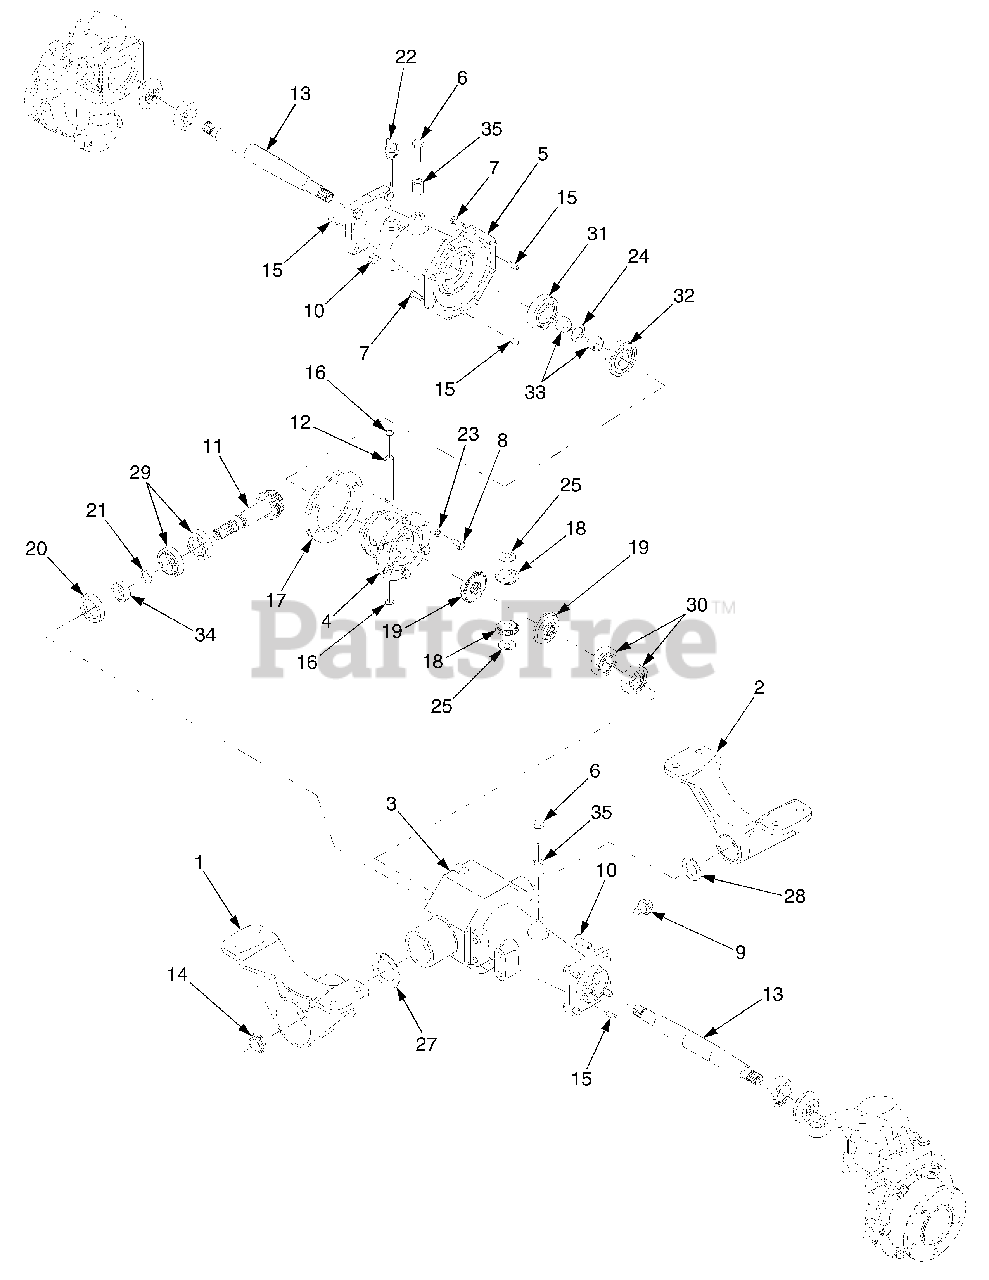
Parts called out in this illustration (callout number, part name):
1	Bracket, Front Axle Mtg. - Rear
2	Bracket, Front Axle Mtg. - Front
3	Housing, Main Axle RH
4	Housing, Differential
5	Housing, Axle LH
6	Screw, Hex Cap, M10-1.5 x 35 GR8.8
7	Screw, Hex Cap, M8-1.25 x 25 GR8.8
8	Screw, Hex Cap, M8-1.25 x 14 GR8.8
9	Plug, Screw, M14-1.5 x .827
10	Screw, Hex Lock, M10-1.5 x 30
11	Shaft, Input, 6T
12	Shaft, Cross
13	Shaft, Axle
14	Nut, Special, 24mm
15	Pin, Dowel, 8mm x 20mm
16	Ring, Internal Retaineng, 14mm
17	Gear, Bevel, 34T
18	Gear, Miter, 10T
19	Gear, Miter, 16T
20	Seal, Oil, 52mm x 35mm x 10mm
21	O-Ring, 19mm x 3mm
22	Dipstick, Front Axle
23	Washer, Flat, .33 x .63 x .0635
24	Washer, Flat, .793 x 1.24 x .06 Hdn.
25	Washer, Special Spherical
26	Washer, Flat, .793 x 1.37 x .005
26	Washer, Flat, .793 x 1.37 x .010
26	Washer, Flat, .793 x 1.37 x .015
26	Washer, Flat, .793 x 1.37 x .020
26	Washer, Flat, .793 x 1.37 x .025
27	Washer, Thrust, 1.66 x 2.59 x .059
28	Washer, Thrust, 1.03 x 1.73 x .059
29	Bearing, Tapered Roller w/ Race
30	Bearing, Ball
31	Bearing, Ball
32	Bearing, Ball
33	Spacer, 20 x 25 x 16mm
34	Spacer, 25 x 35 x 12mm
35	Spacer, .5 x .75 x .86
